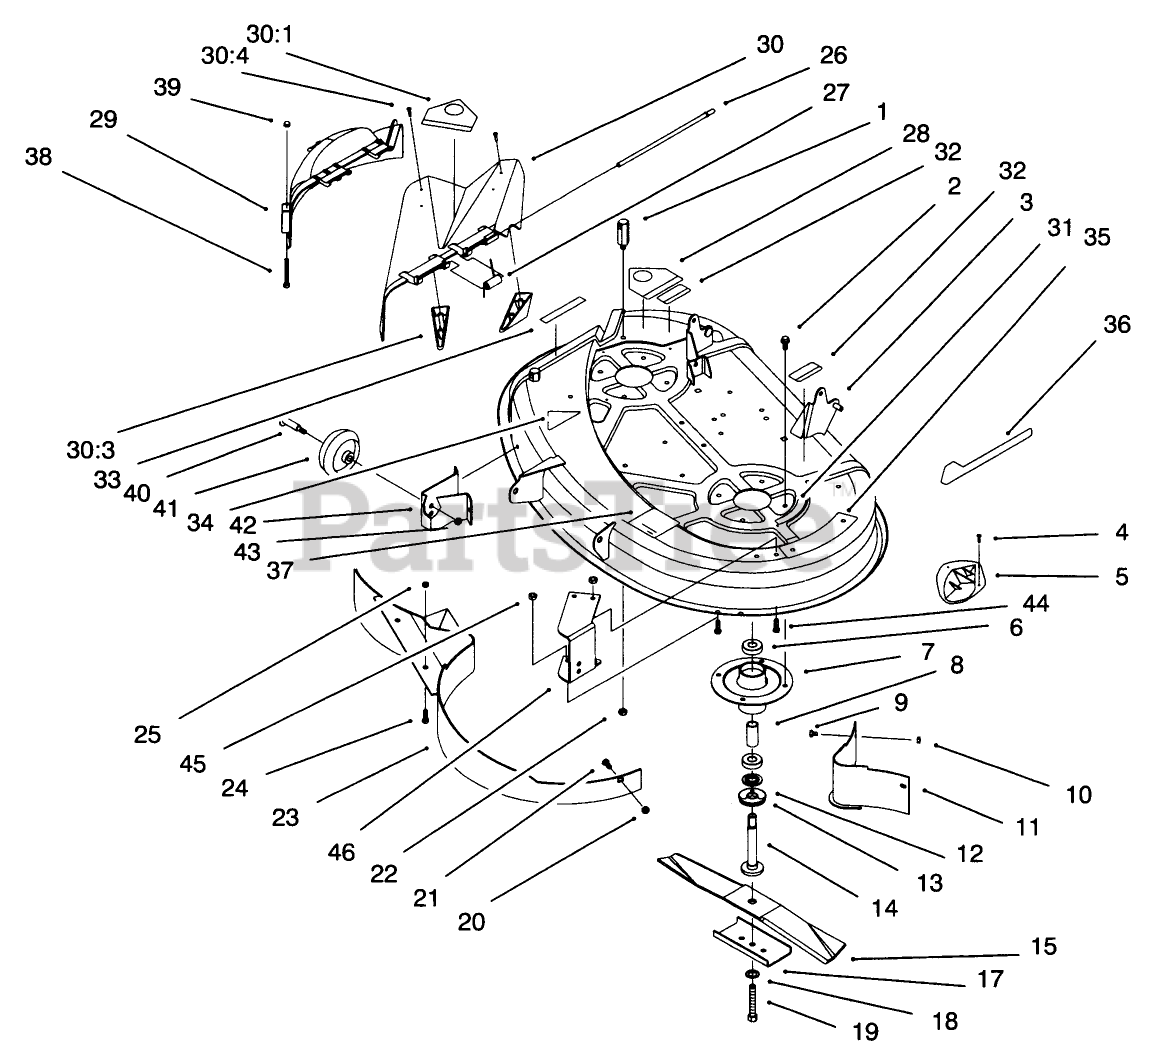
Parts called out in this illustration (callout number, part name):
1	REAR PIVOT POST (PLTD)
2	SCREW-TAPTITE
3	Deck Wa-38"
4	SCREW-PPH
5	PLATE-KICKER
6	BEARING-BALL
7	HOUSING-SPINDLE
8	SPACER
9	SCREW-HH
10	NUT-LOCK, NI
11	BAFFLE ASM
12	SPACER
13	SHIELD-BEARING
14	SHAFT-SPINDLE
17	STIFFENER-BLADE
18	WASHER-BELLEVILLE
19	SCREW-HH
20	NUT-LOCK, NI
21	BOLT-CARR
22	NUT-LOCK, NI
23	BAFFLE ASM
24	SCREW-HH
25	NUT-LOCK, NI
26	ROD-HINGE DEFLECTOR
27	SPRING
28	DECAL-DANGER
29	COVER-RECYCLER
30	DEFLECTOR ASM
30:1	DECAL-DANGER
30:3	Kicker-CE (Only On: 71217)
30:4	SCREW-PPH
31	DECAL-DANGER, SHIELD
32	DECAL-WARNING
33	DECAL-DANGER, DEFLECTOR
33	DECAL-DANGER
35	DECAL-DANGER
36	DECAL-RECYCLER DECK 38"
38	SCREW-HH
39	NUT-CAP
40	SCREW-SHOULDER, HWH
41	WHEEL-GAGE
42	BRACKET-WHEEL, RH
43	NUT-LOCK, NI
44	SCREW-HH
45	NUT-LOCK, NI
46	BRACKET-WHEEL, LH
